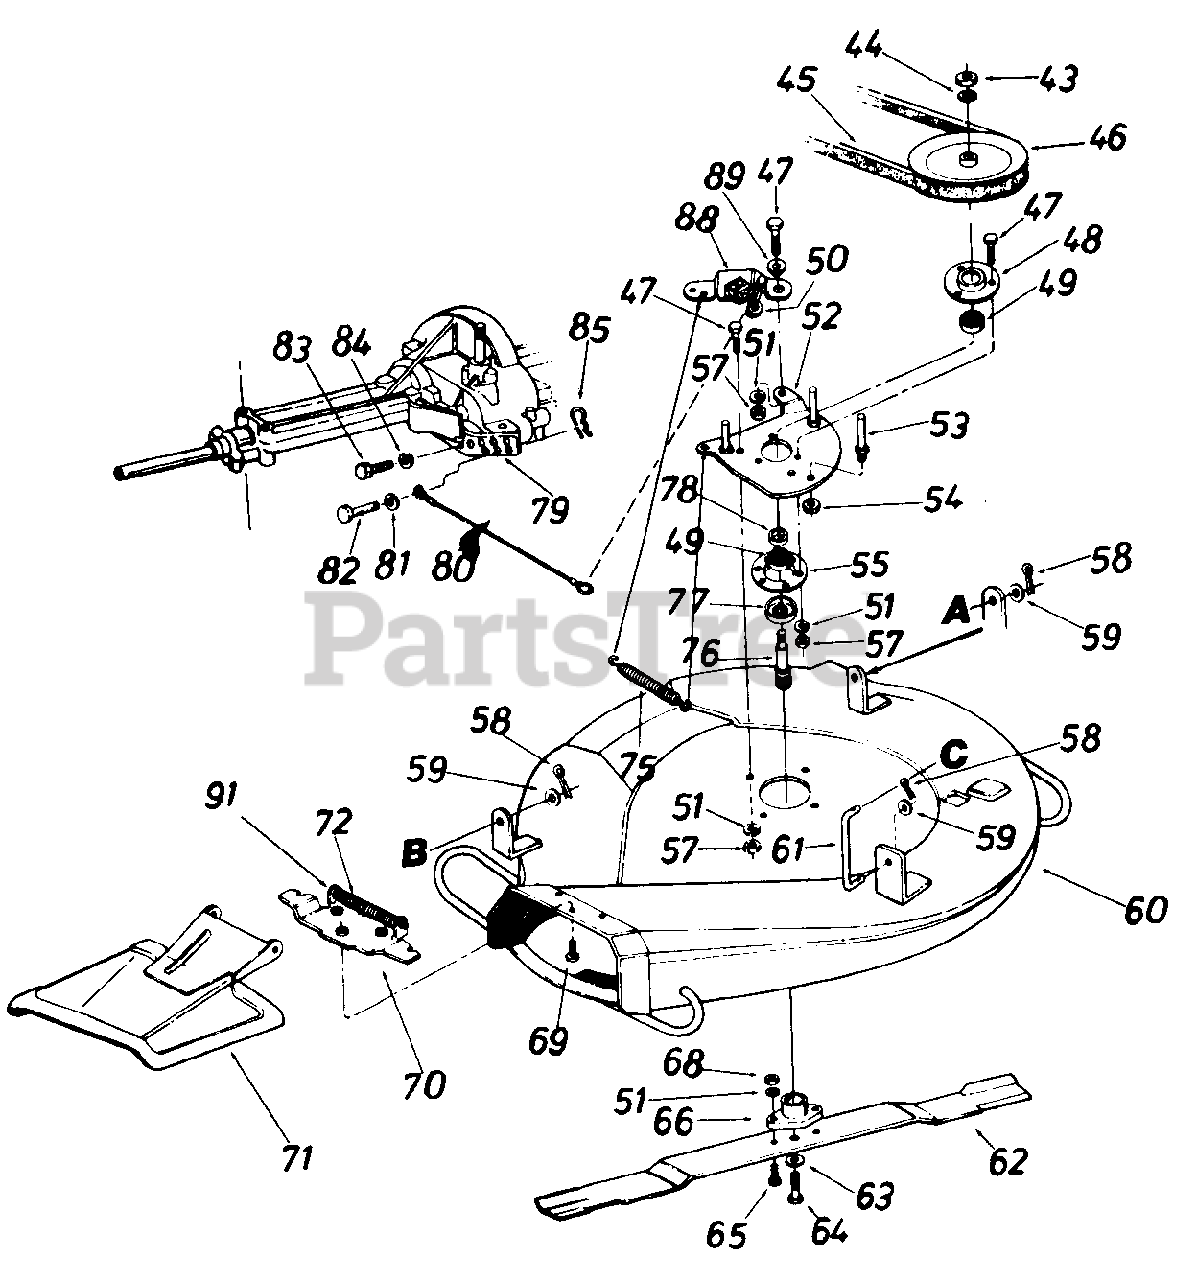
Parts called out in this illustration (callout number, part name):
43	Hex Jam Nut 5/8-18 Thd.
44	Bell-Wash. .63" I.D. x 1.25" O.D.
45	V-Belt 1/2 x 52" Lg.
46	1/2" V-Pulley .625" I.D. x 6.0" O.D.
47	Hex Bolt 5/16-18 x 75"
48	Open Brg. Housing 1.85" I.D.
49	Ball Brg. .787" I.D. x 1.85" O.D.
50	Cap Speed Nut 1/4" Rod
51	L-Wash. 5/16" I.D.
52	Spindle Mtg. Plate
53	Stud 3/8-16 x 3 00" Lg.
54	Hex Jam Nut 3/8-16 Thd.
55	Bearing Housing 1.85" I.D.
57	Hex Nut 5/16-18 Thd.
58	Intern. Cotter Pin 1/2" Dia.
59	Fl-Wash. .385" I.D. x .87"
60	26" Deck Ass'y.
61	Deck Link 3 9" Lg.
62	26" High Lift Blade
63	Bell-Wash. .39" I.D. x 1.38"
64	Hex Bolt 3/8-24 x 1.0"
65	Hex Bolt Spec. 5/16-24 x 1.0" Lg
66	Blade Adapter
68	Hex Nut 5/16-24 Thd.
69	Hex Wash. S-Tap Scr. 1/4-20 x.50" Lg.
70	Adapter Plate-Chute
71	Chute Cover Ass'y. Comp.
72	Torsion Spring
75	Extension Spring 3 25" Lg.
76	Blade Spindle 4.42" Lg.
77	Bearing Shield
78	Spacer 1.0" O.D. x 35" Lg.
79	Lower Inside Belt Guard
80	Brake Cable 11.75" Lg.
81	Fl-Wash. .281" I.D. x 60"
82	Clevis Pin 1/4" Dia. x 53" O.D.
83	Hex Bolt 1/4-20 x .62" Lg.
84	L-Wash. 1/4" I.D.
85	Intern. Cot.-Pin 5/16" Dia.
88	Blade Brake Brkt. Ass'y.
89	Shld. Spacer.27" Lg.
91	Hinge Pin
